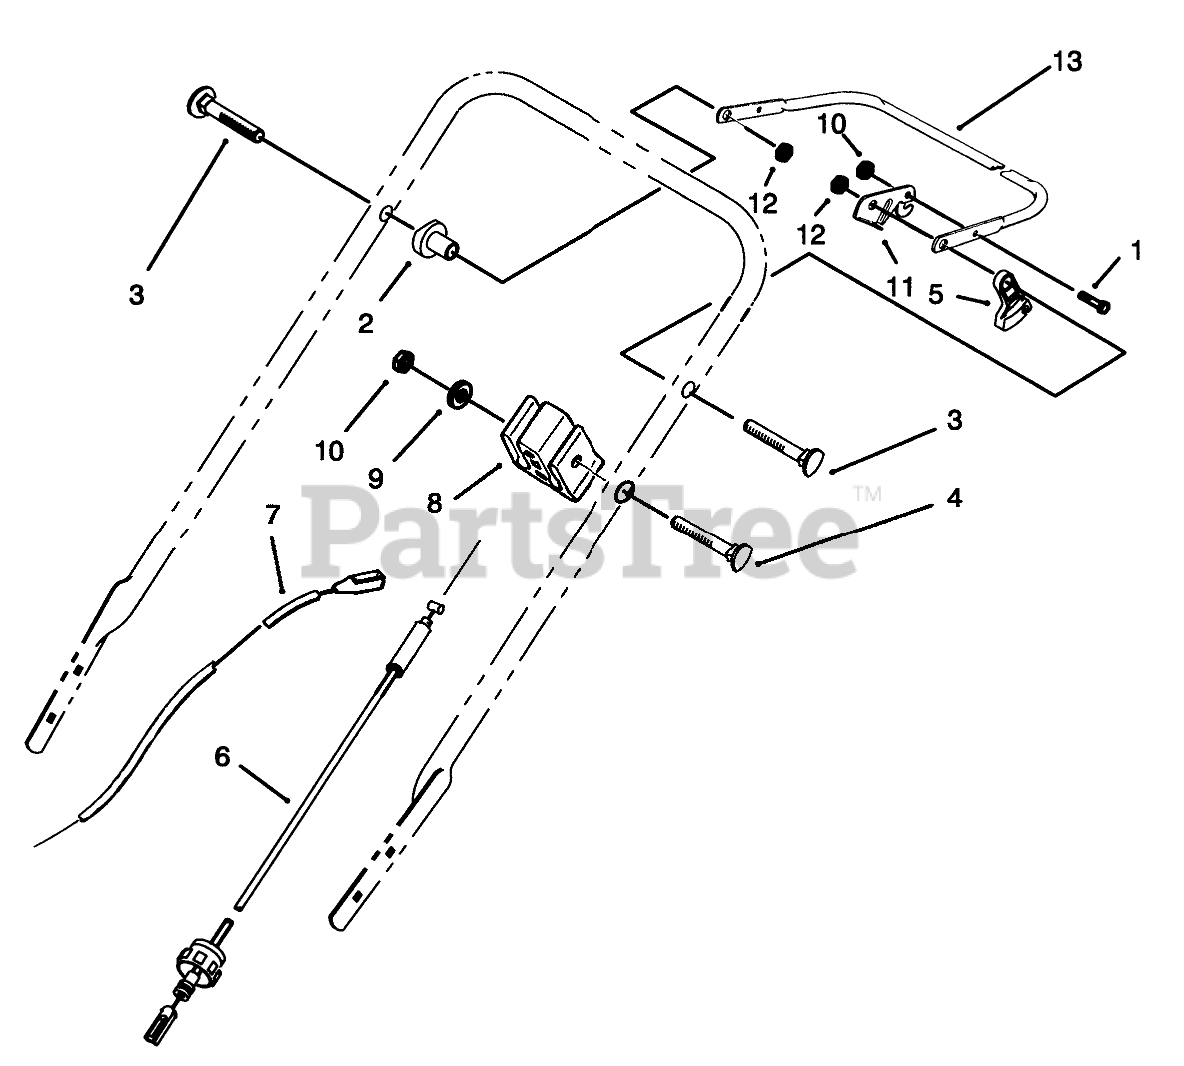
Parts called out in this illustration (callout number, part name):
1	SCREW-HH
2	SPACER-SUPPORT
3	SCREW-HANDLE
4	SCREW-HANDLE
5	LEVER-TRACTION
6	CABLE-TRACTION
7	BRAKE CONTROL
8	SUPPORT-CABLE
9	WASHER-FLAT
10	NUT-LOCK, NI
11	Lever-Control
12	NUT-LOCK NI
13	Bar-Control
